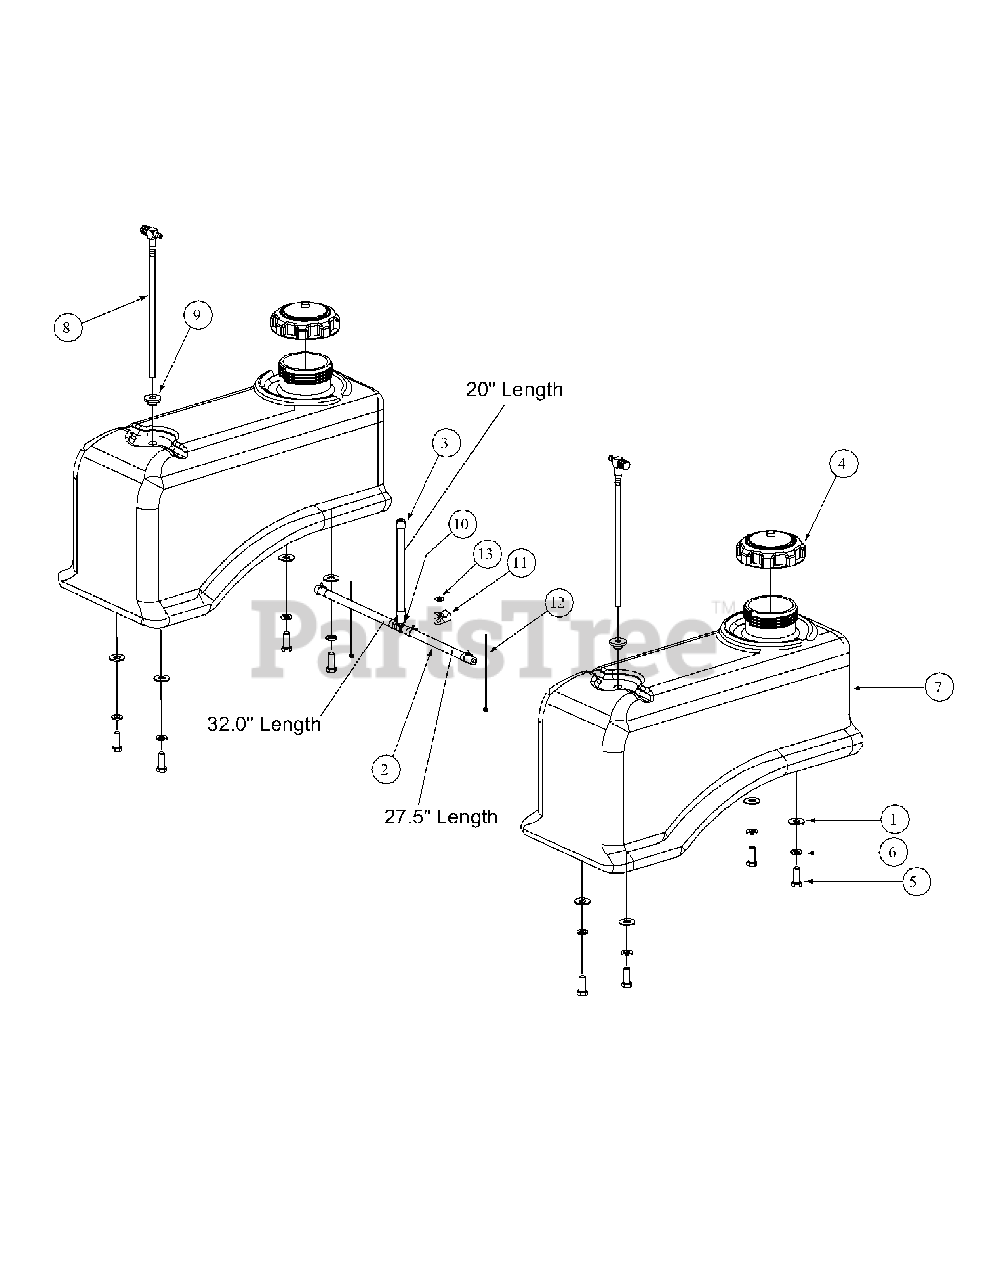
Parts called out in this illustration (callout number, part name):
1	Flat Washer, .406 ID, 1.0 OD, .105
2	Hose, 1/4" Fuel Line 79.5"
3	Clamp, Union
4	Fuel Cap, 3.5
5	Hex, Cap Screw, 3/8-16, .88
6	Lock Washer, 3/8
7	Fuel Tank
8	Fuel Fitting
9	Fuel Tank Grommet
10	Tee Fitting, Fuel
12	Cable Tie
13	Flatwasher 1/4 x .630 x .0515
